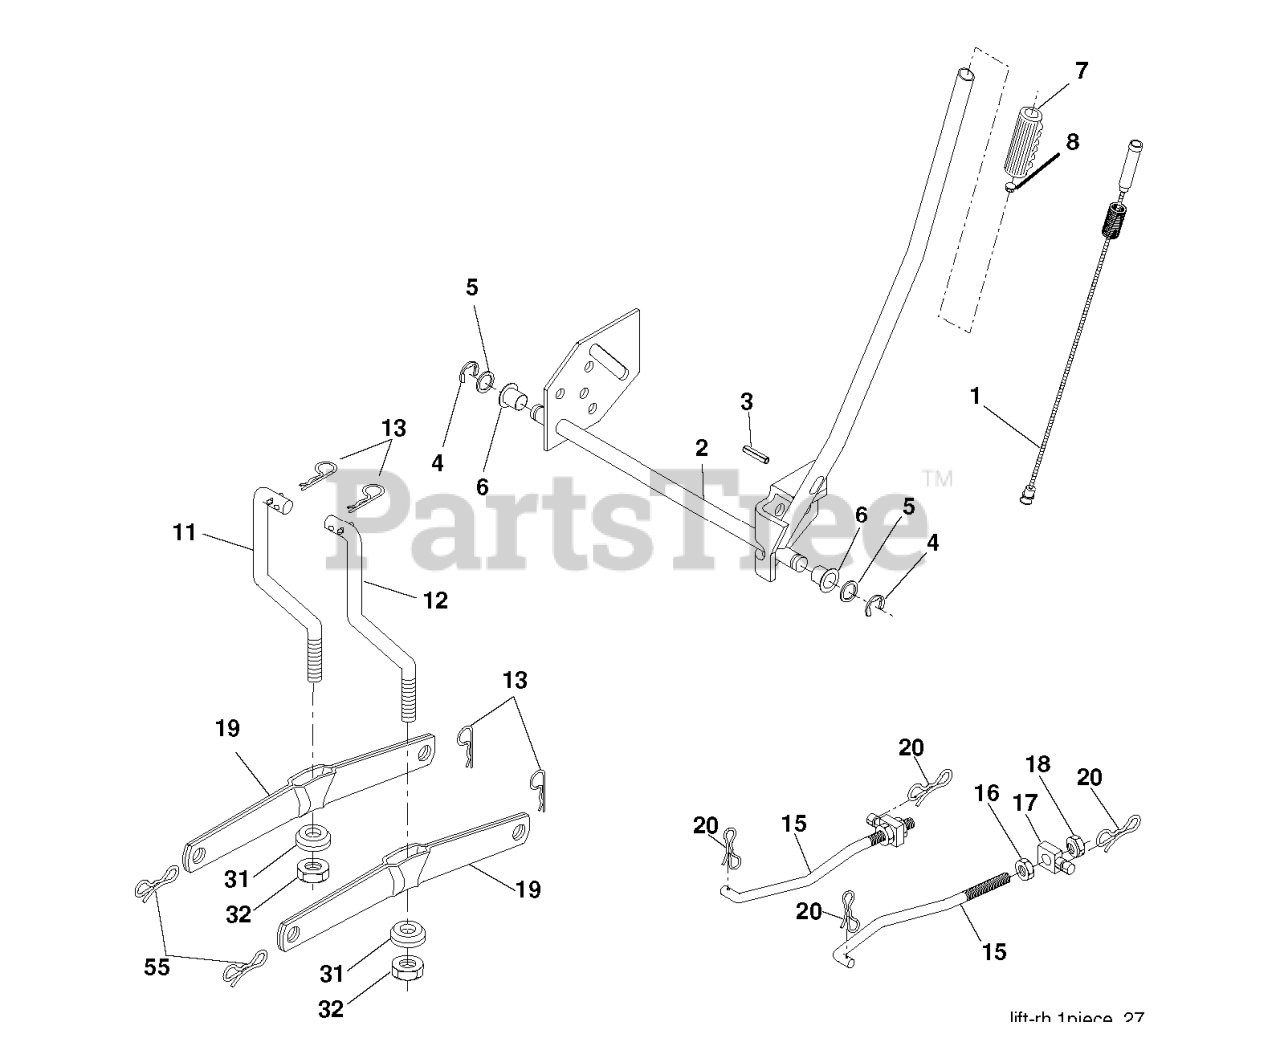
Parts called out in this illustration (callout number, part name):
1	PLUNGER.ASM.LIFT.LVR.BLK.17.32
2	SHAFT ASM R HANDLE
3	PIN GROOVE.
4	RETAINING RING LT
6	BEARING.NYLON
8	PLUNGER BUT KIT
11	LINK LIFT LH
12	LINK LIFT RH
13	RETAINER-SPRNG RB
15	LINK.SUSPENSION.FRONT
16	NUT.HEX.JAM.1/2-13
18	NUT.LK.W/WSH.1/2.
19	ARM.REAR.SUSPENSION
20	PIN.COTTER.7/16.BOW TI.
31	BEARING.PIVOT.LIFT
32	NUT CROWNLOCK 3/8-24
55	PIN.COTTER.5/16.BOW TI
